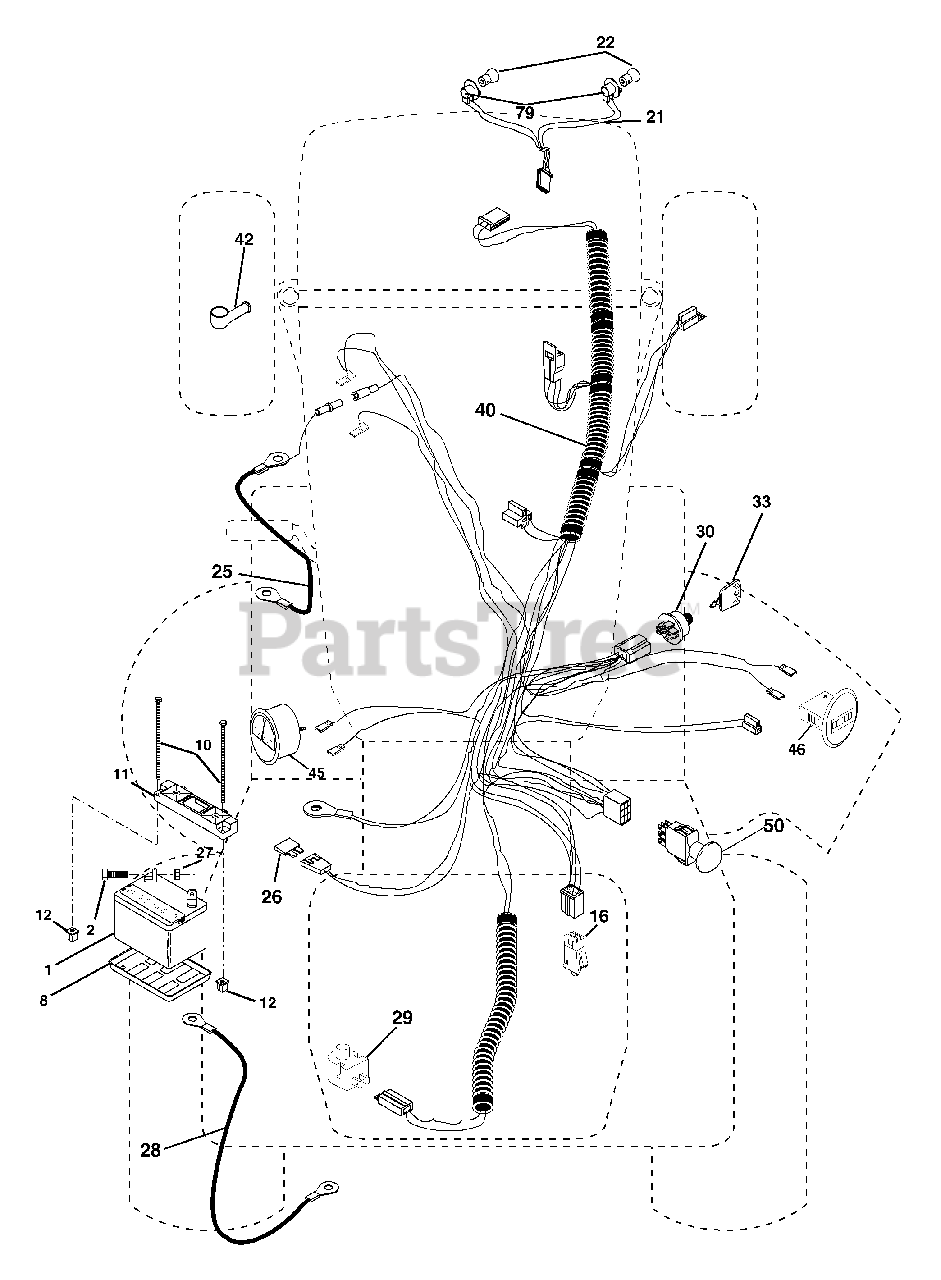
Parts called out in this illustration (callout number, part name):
1	Battery
2	Bolt Hex Head 1/4-20 x 3/4
8	Tray, Battery
10	Bolt, Battery Front 1/4-20 x 7.5 Zinc
11	Holddown Battery Front Mount
12	Nut, Push Nylon 1.4" Battery Front
16	Switch Interlock
21	Harness Socket Light w/4152J
22	Bulb Light
25	Cable, Battery
27	Nut Keps Hex 1/4-20
28	Cable, Ground
29	Switch, Plunger NC Gray
30	Switch, Ign
40	Harness Ign.
42	Cover, Terminal Red
46	Hourmeter Snap-In
50	Switch, PTO
79	Bulbholder Asm
